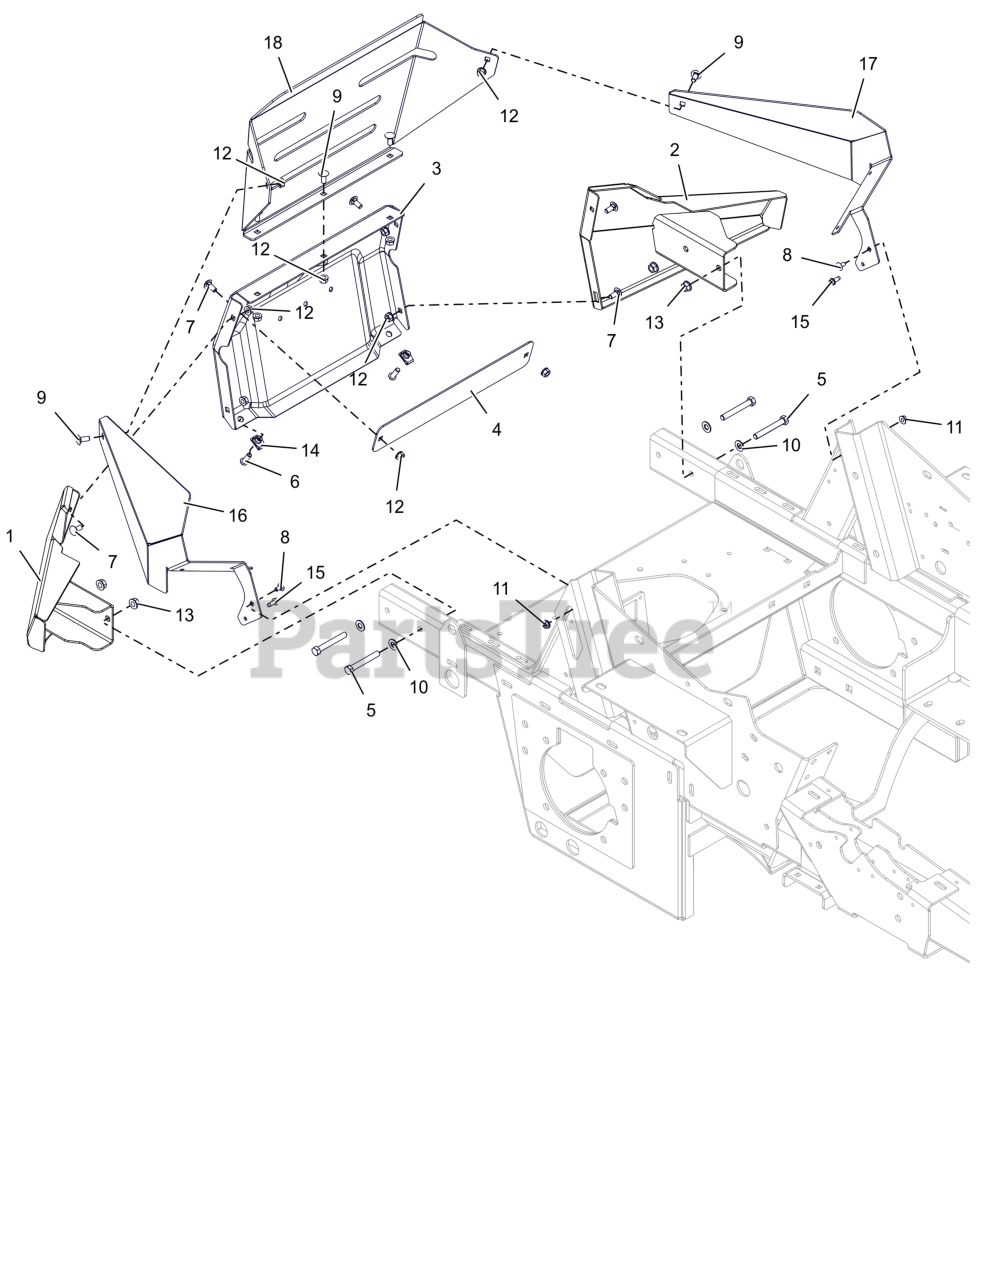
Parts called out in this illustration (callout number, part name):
1	WLDMT, RIGHT REAR BUMPER WING (RED) W/ SAFETY DECALS
2	WLDMT, LEFT REAR BUMPER WING (RED) W/ SAFETY DECALS
3	BUMPER, COMMERCIAL REAR
4	PLATE, BACKER (BLACK)
5	BLT, HEX .38-16X2.75 G5 ZCC
6	BLT,SHCS-BTN .31-18X1.00 ZCC
7	BLT,RHSN .31-18X.75 G5 ZCC
8	BLT, RHSSN.25-20X.500 G5 ZCC
9	BLT, RHSSN.31-18X.750 G5 ZCC
10	WSHR,FLT .406X.812X.065 ZCC
11	NUT-LK-CTR-FLG .25-20 ZC120
12	NUT,LK-CTR-FLG .31-18 GF ZCC
13	NUT-LK-CTR-FLG .375-16 GF ZCC
14	NUT-CLIP RETAINER 5/16-18X.56
15	SCR,TAP .25-20X.625 HWH ZCC
16	BRKT- RH SIDE WRAP MTG
17	BRKT- LH SIDE WRAP MTG
18	WRAP- REAR CENTER
